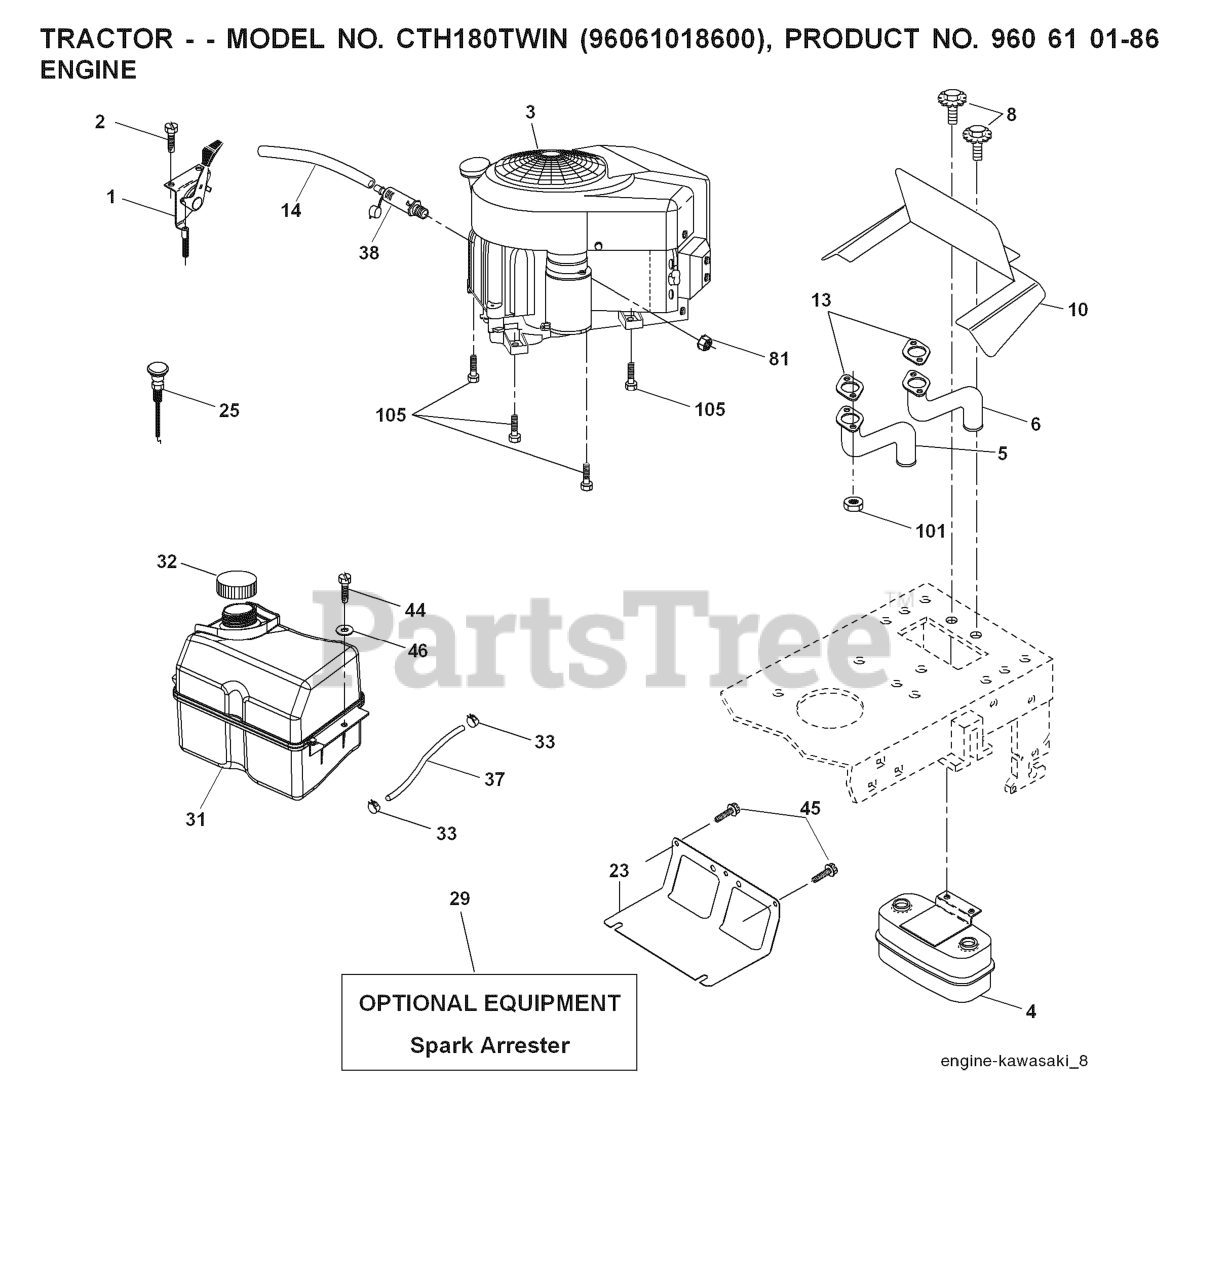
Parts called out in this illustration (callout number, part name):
1	CONTROL, THROTTLE
2	SCREW
4	MUFFLER.TWIN.CYL.LOW.TONE
5	EXHAUST.TUBE.LH.KAWASAKI.
6	EXHAUST.TUBE.RH.KAWASAKI.
8	BOLT.5/16-18UNCX3/4 W/SEMS.BLK
10	RP SHIELD HEAT MUFFLER
14	TUBE, DRAIN OIL ASM.
23	SHIELD.BROWNING.DBR.GUARD
25	CONTROL, CHOKE
29	KIT.SPARK ARRESTOR 794945 B&S
31	TANK FUEL
32	FUEL CAP
33	HOSE CLAMP
37	LINE.FUEL.20
44	SCREW HEXWSHR 1/4-20X3/4
45	SCREW, 3/8-16X3/4
81	NUT
101	NUT.HEX.FLANGE.TOPLOCK
105	SCREW 3/8-16X1
